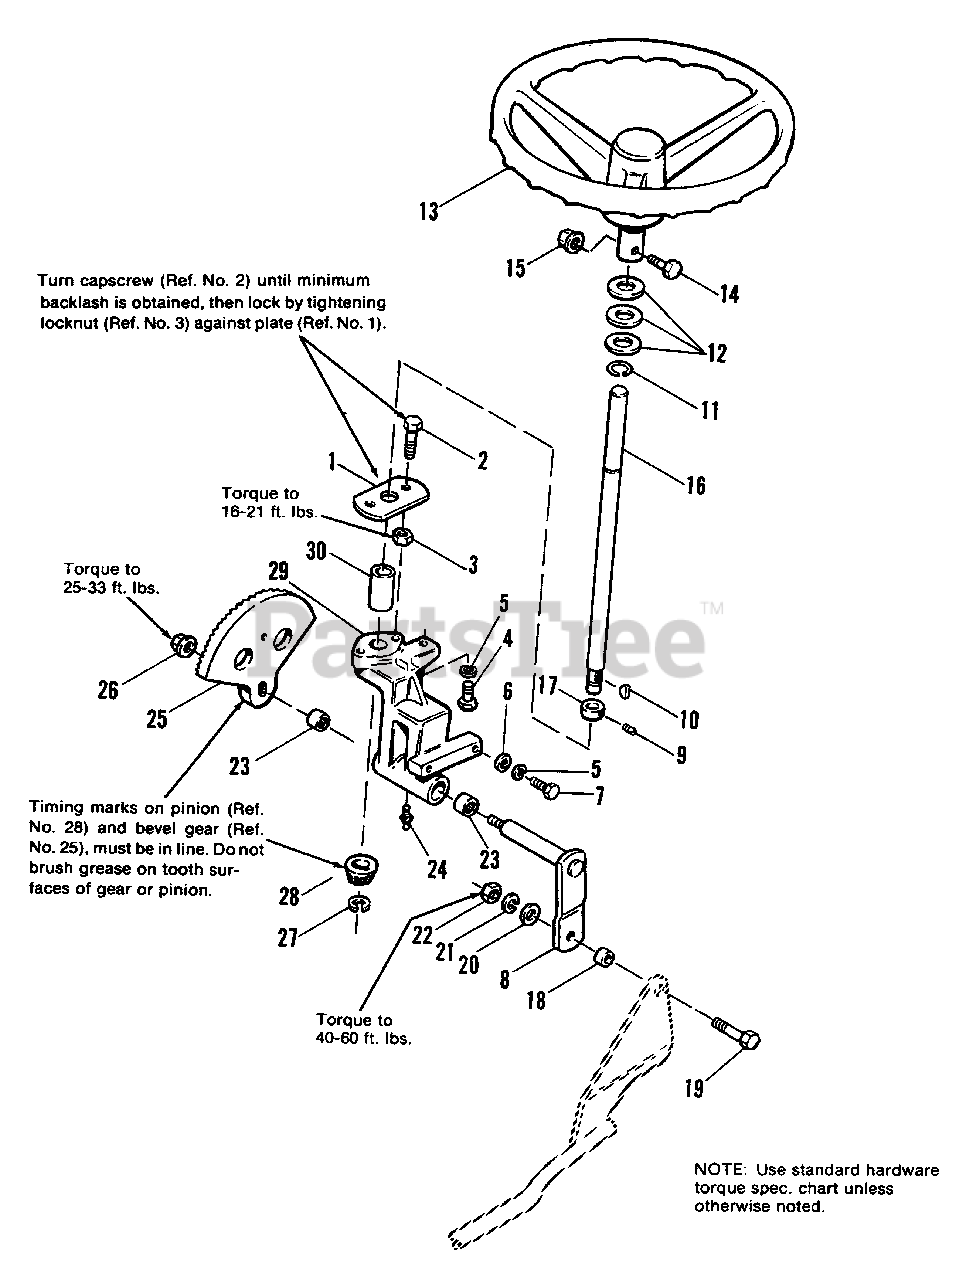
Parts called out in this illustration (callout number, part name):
1	PLATE, Steering
2	CAPSCREW, Hex Hd., 3/8-16 x 1-1/4
3	LOCKNUT, Hex, Jam, 3/8-16
4	CAPSCREW, Hex, 3/8-16 x 3/4
5	LOCKWASHER, 3/8
6	WASHER, Plain, 3/8
7	CAPSCREW, Hex Hd., 3/8-16 x 7/8
8	ARM ASSY., Steering
9	SETSCREW, Skt. Hd., 5/16-18 x 1/4
10	KEY, Woodruff #6, 5/32 x 5/8
11	RING, Retaining
12	WASHER, Nylon, 3/4
13	WHEEL, Steering
14	CAPSCREW, Hex Hd., 5/16-18 x 1-1/4
15	LOCKNUT, Flange, 5/16-18
16	SHAFT, Steering
17	COLLAR, Set
19	CAPSCREW, Hex Hd., 1/2-13 x 1-1/2
20	WASHER, Plain
21	LOCKWASHER, 1/2
22	NUT, Hex, 1/2-13
23	BEARING, Needle
24	FITTING, Grease
25	GEAR, Bevel
26	LOCKNUT, Hex, Flange, 7/16-14
27	"E" RING
28	PINION, Bevel
29	HOUSING ASSY., Steering
